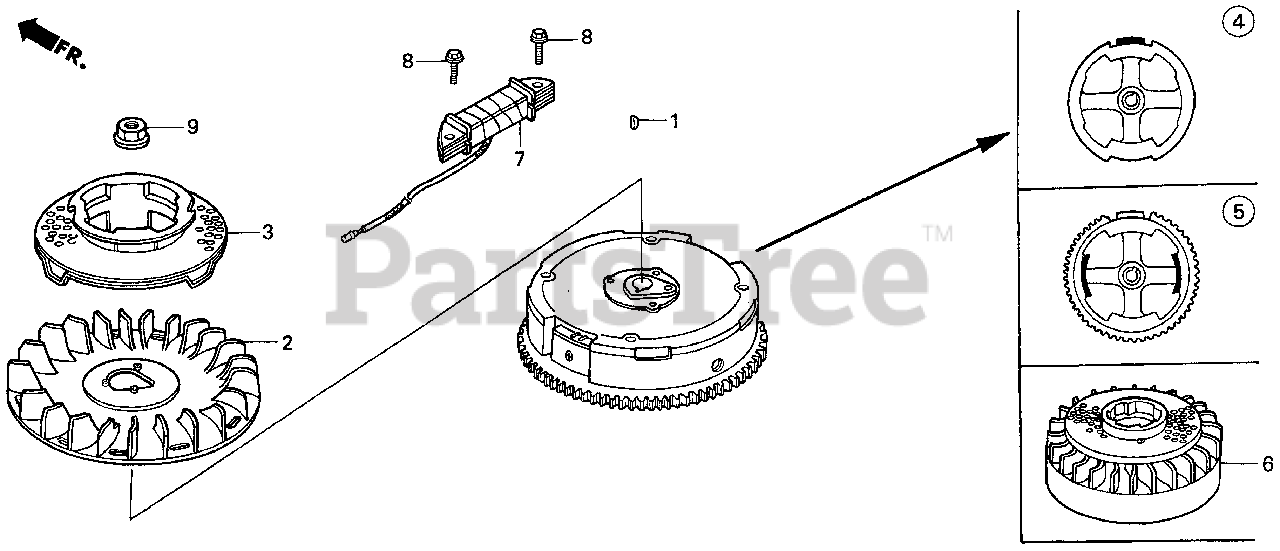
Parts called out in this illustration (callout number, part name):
1	KEY, SPECIAL WOODRUFF (25X18)
6	FLYWHEEL ASSY.
9	NUT, SPECIAL (14MM)
